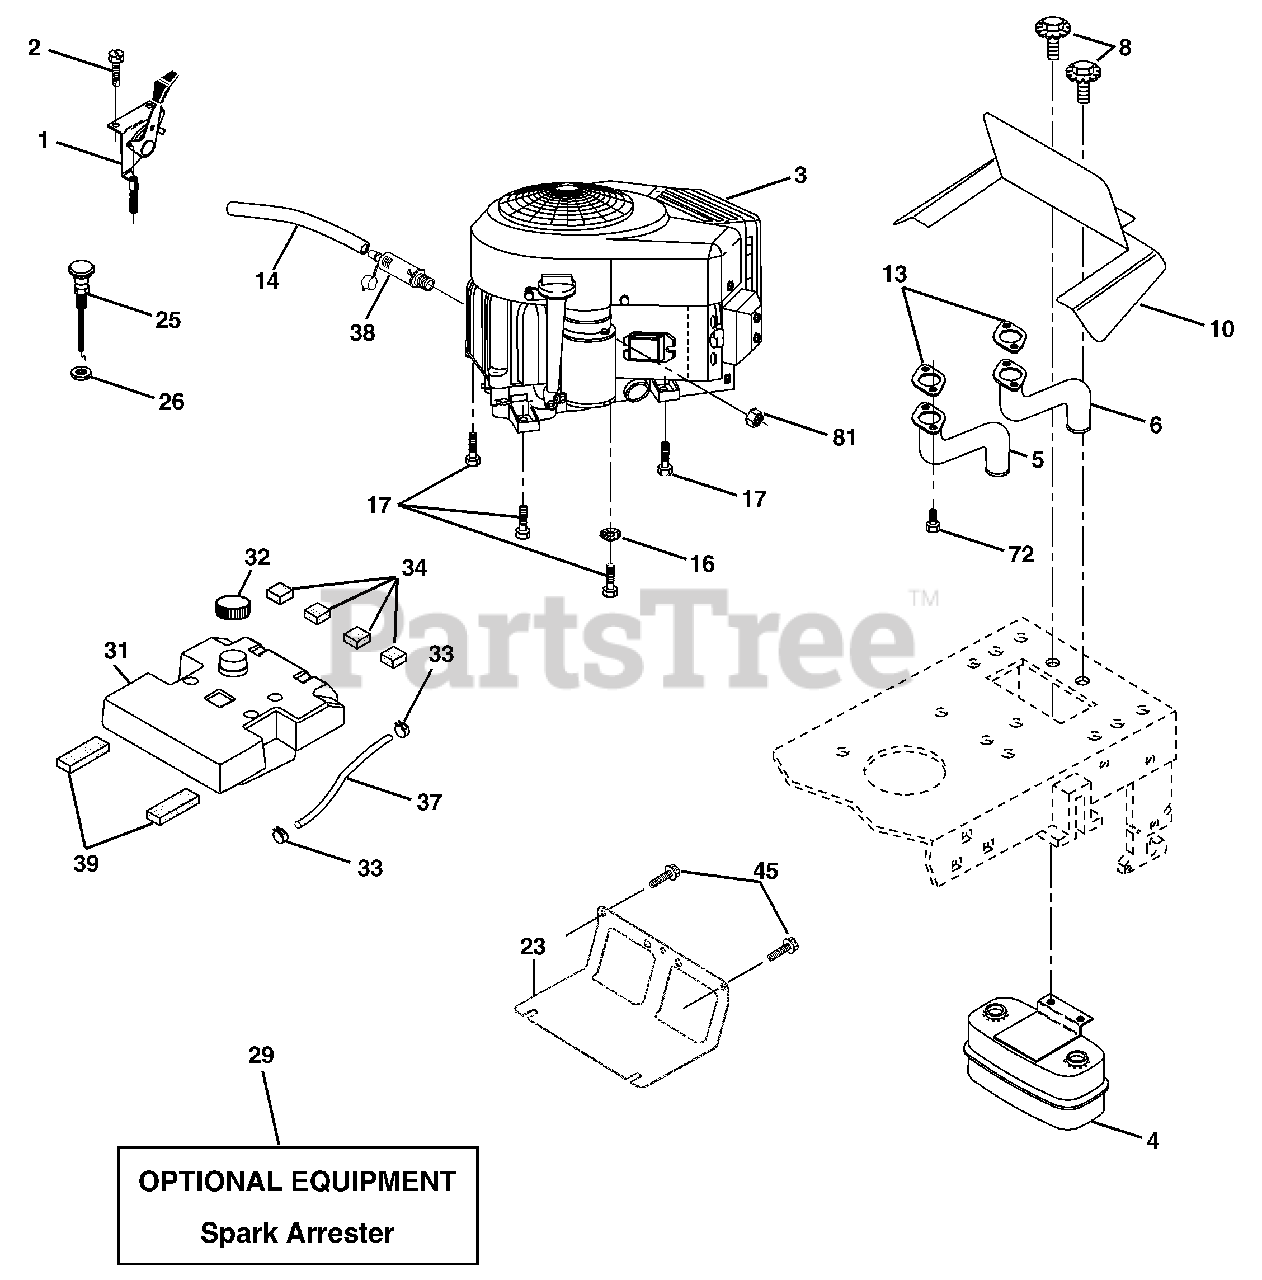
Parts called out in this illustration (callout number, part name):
1	Control Throttle
2	Screw Hwhd Hi-Lo #13-16 x 3/4
4	Muffler Asm Twin Lo-Tone
5	Pipe Exhaust LH Intek
6	Pipe Exhaust RH Intek
8	Bolt 5/16-18 Unc x 3/4 w/Sems
10	Shield Browning Intek II
13	Muffler Gasket
16	Washer Lock Ext Tooth 3/8
17	Screw Thdrol 3/8-16 x 1-1/2
23	Shield Heat
25	Choke Control
26	Nut, Keps 3/8-24 Unf
29	Kit Spark Arrestor (Flat Scrn)
31	Tank Fuel 3 50 Rear
32	Cap Asm Fuel W/sym Vented
33	Clamp Hose Black
34	Pad, Spacer
37	Line Fuel
38	Plug Drain Oil Easy
39	Pad Idler
45	Screw Hexwsh Thdr 3/8-16 x 3/4
72	Screw Socket Head 5/16-18 x 1
81	Nut Keps Hex 1/4-20 Unc
